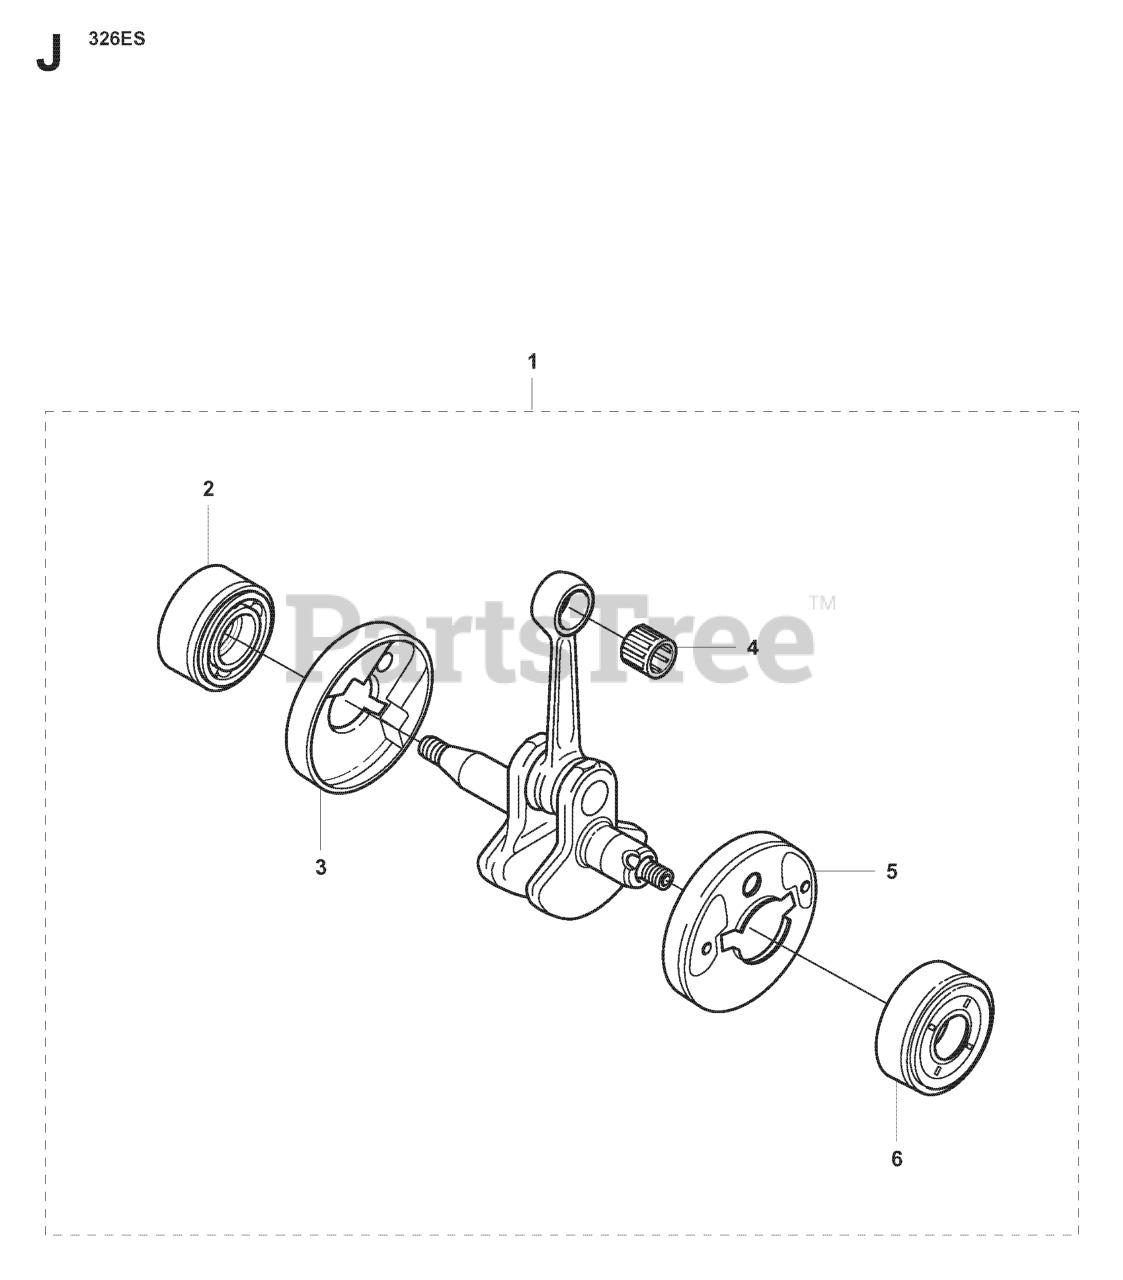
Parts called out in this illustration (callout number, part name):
1	CRANKSHAFT
2	BEARING CAP
6	BEARING CAP
